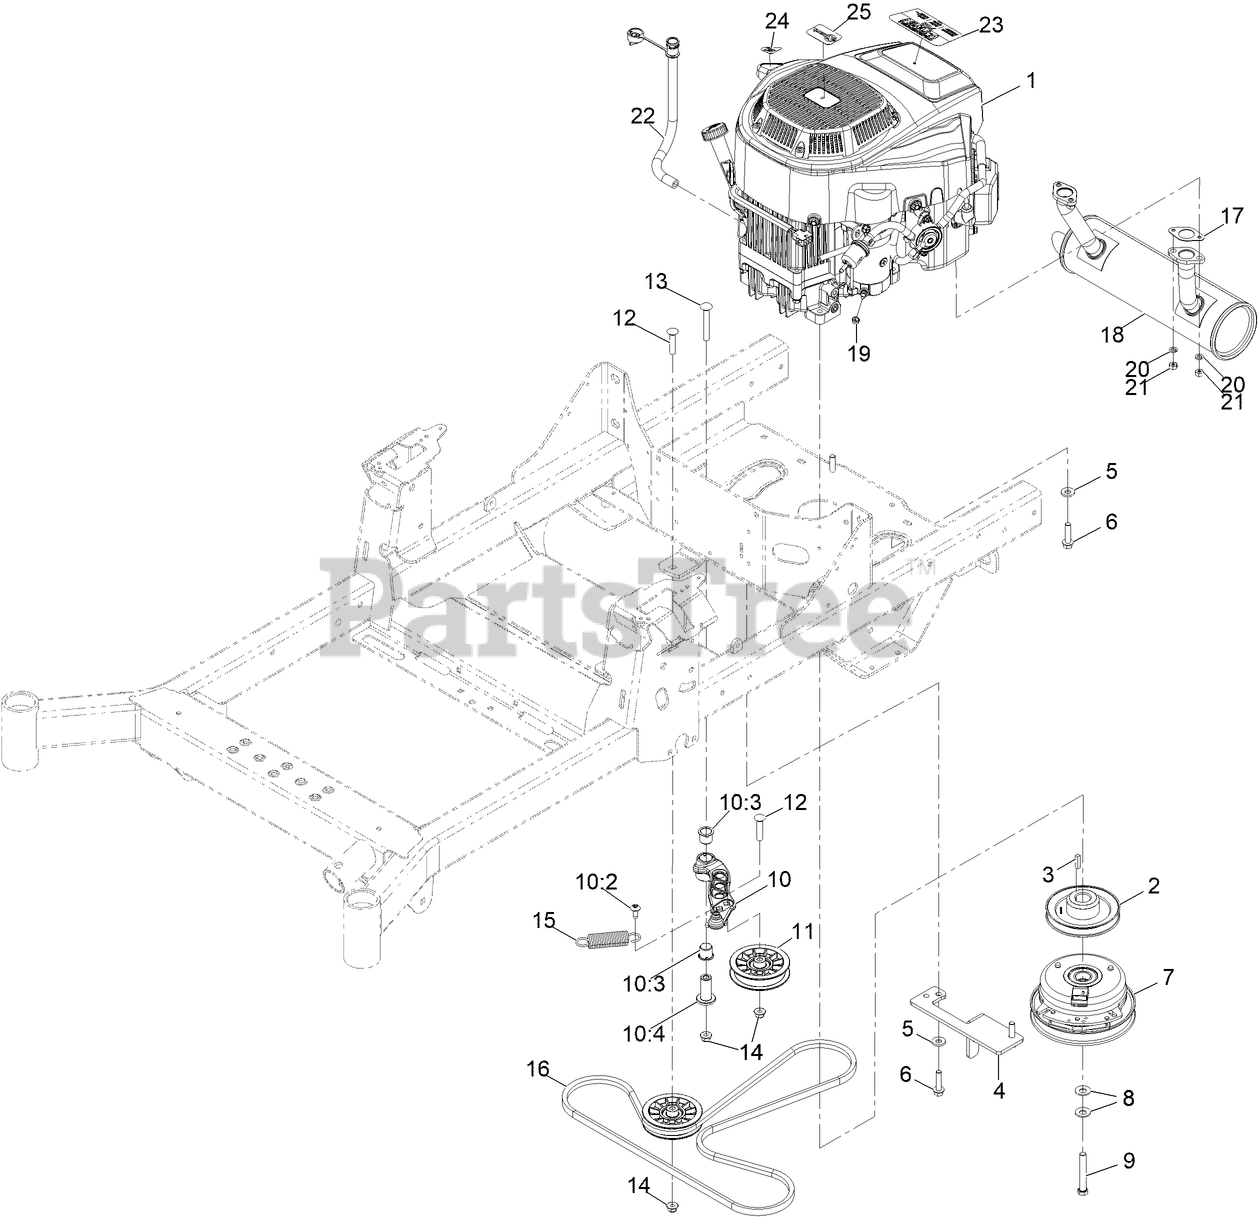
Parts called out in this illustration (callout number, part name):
1	ENGINE-2P77F
2	SHEAVE, ENGINE
4	Anchor-Clutch
5	WASHER-BELLEVILLE
6	SCREW-HWH
7	CLUTCH - 1.00 HD
8	WASHER-SPRING
9	SCREW-HH W/LOCTITE
10	ASM, PUMP IDLER
10:2	SCREW, TAPTITE
10:3	BUSHING, IGUS
10:4	Spacer, Idler Pivot
11	PULLEY-FLAT IDLER
12	SCREW-CARR
13	SCREW-CARR
14	NUT-HF, NI
15	SPRING-EXTENSION
16	BELT-V
17	GASKET-EXHAUST
18	MUFFLER, LONCIN
20	WASHER-LOCK, SPLIT
22	OIL DRAIN SERVICE KIT
23	DECAL-ENGINE 708 V-TWIN EXMARK
24	DECAL-DRAIN, OIL
